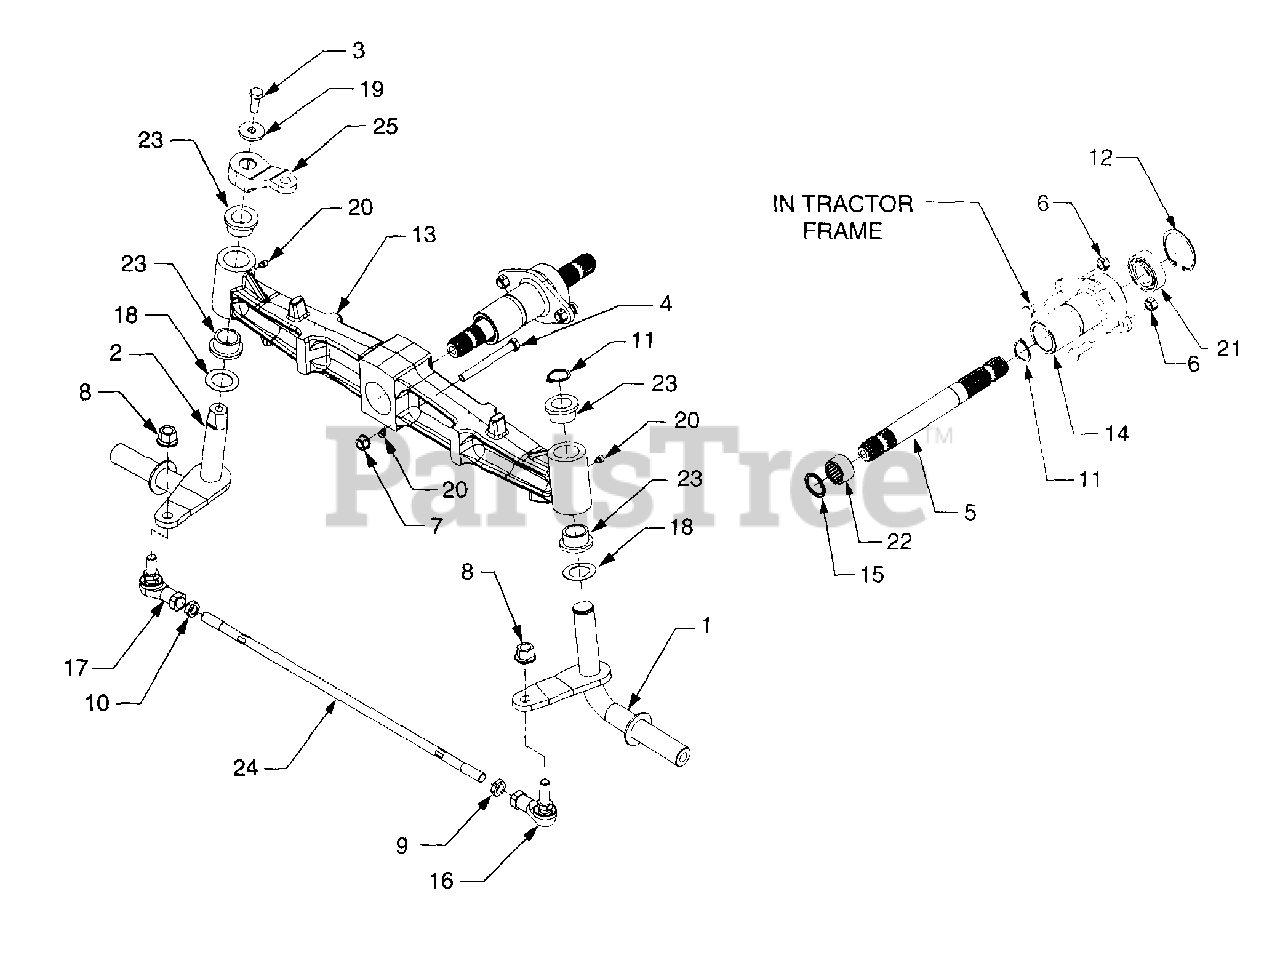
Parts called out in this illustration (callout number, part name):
4	Screw, Hex Cap 3/8-16 x 3.5 GR5
5	Shaft, Splined
6	Nut, Hex Center Lock, 3/8-24
7	Nut, Hex Flange Lock, 3/8-16
8	Nut, Hex Flange Lock, M12 x 1.75
9	Nut, Hex - RH, M12 x 1.75
10	Nut, Hex - LH, M12 x 1.75
11	Snap Ring, 1.0 Dia. Shaft
12	Retaining Ring, Internal, 2.0
13	Pivot Axle
14	Axle Carrier
15	Seal, Grease, 1.31 x 1.0
16	Ball Joint, 12MM x 1.75 RH
17	Ball Joint, 12MM x 1.75 LH
18	Washer, Flat, 1.03 x 1.62 x .030
19	Washer, Flat, .406 x 1.25
20	Fitting, Lube, 3/16 Drive
21	Bearing, Ball
22	Bearing, Needle
23	Bearing, Flange
24	Tie Rod, M12 x1.75 RH & LH
25	Steering Arm
